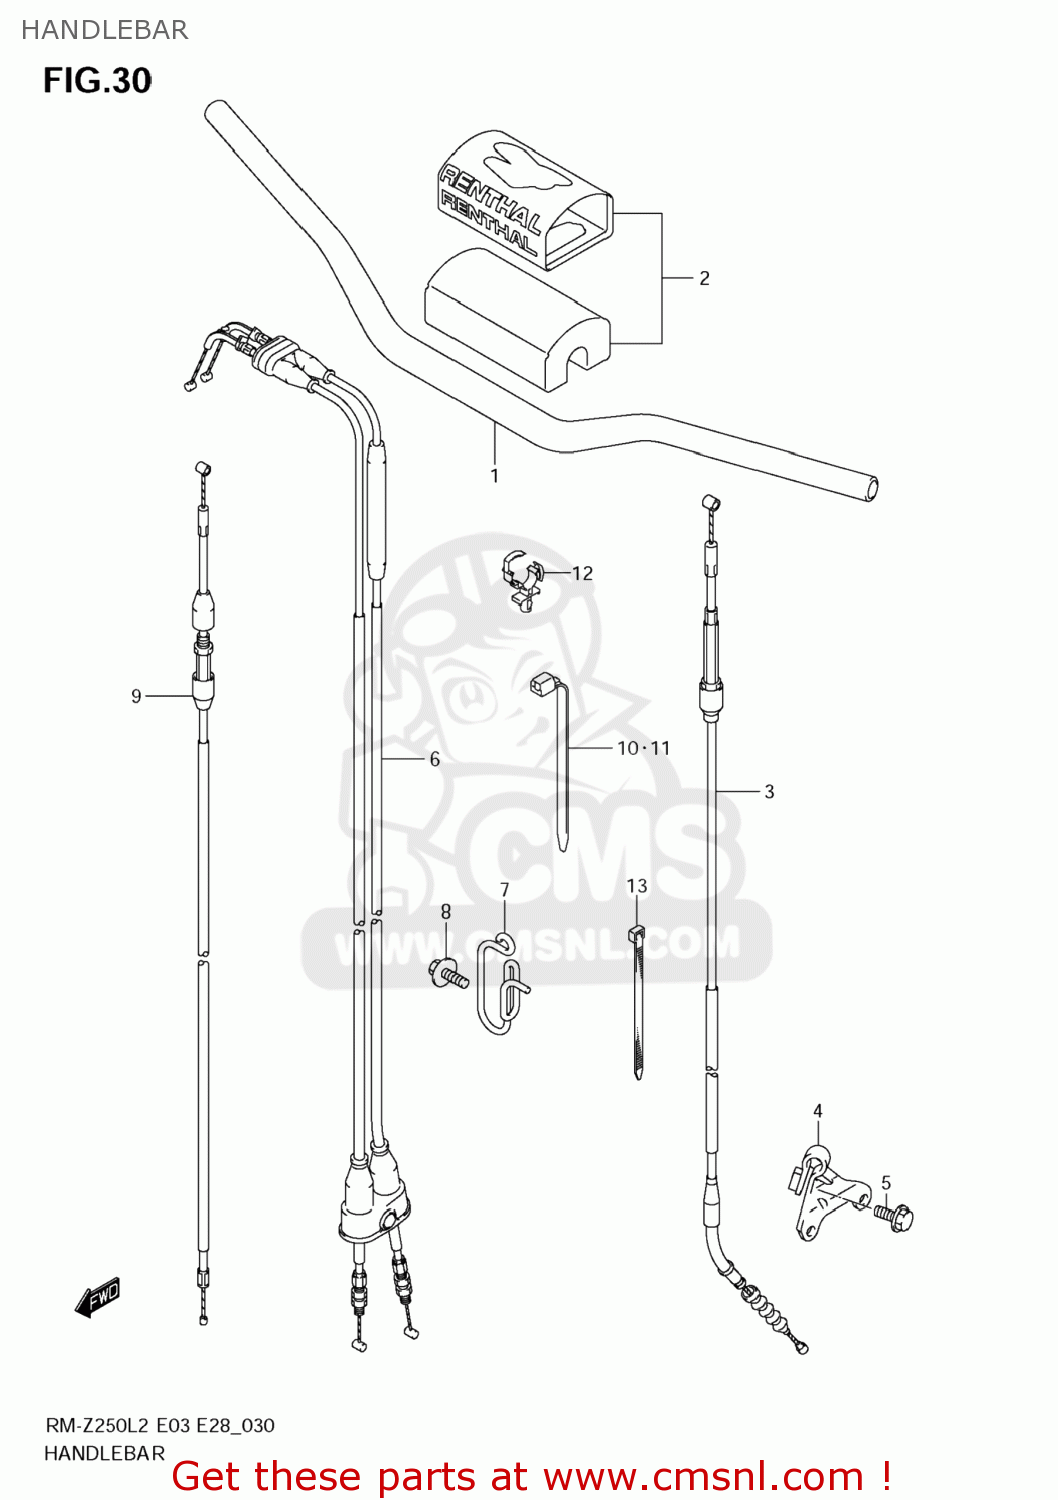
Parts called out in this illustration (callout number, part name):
1	HANDLEBAR
2	PAD SET,HANDLEBAR (NAS)
3	CABLE ASSY,CLUTCH
4	BRACKET,CLUTCH CABLE
5	BOLT
6	CABLE SET,THROTTLE
7	GUIDE,THROTTLE & STARTER CABLE
8	SCREW(6X16)
9	CABLE ASSY,HOT STARTER
10	CLAMP(L:125)
11	CLAMP(L:154)
12	CLAMP
13	CLAMP(L:145)
